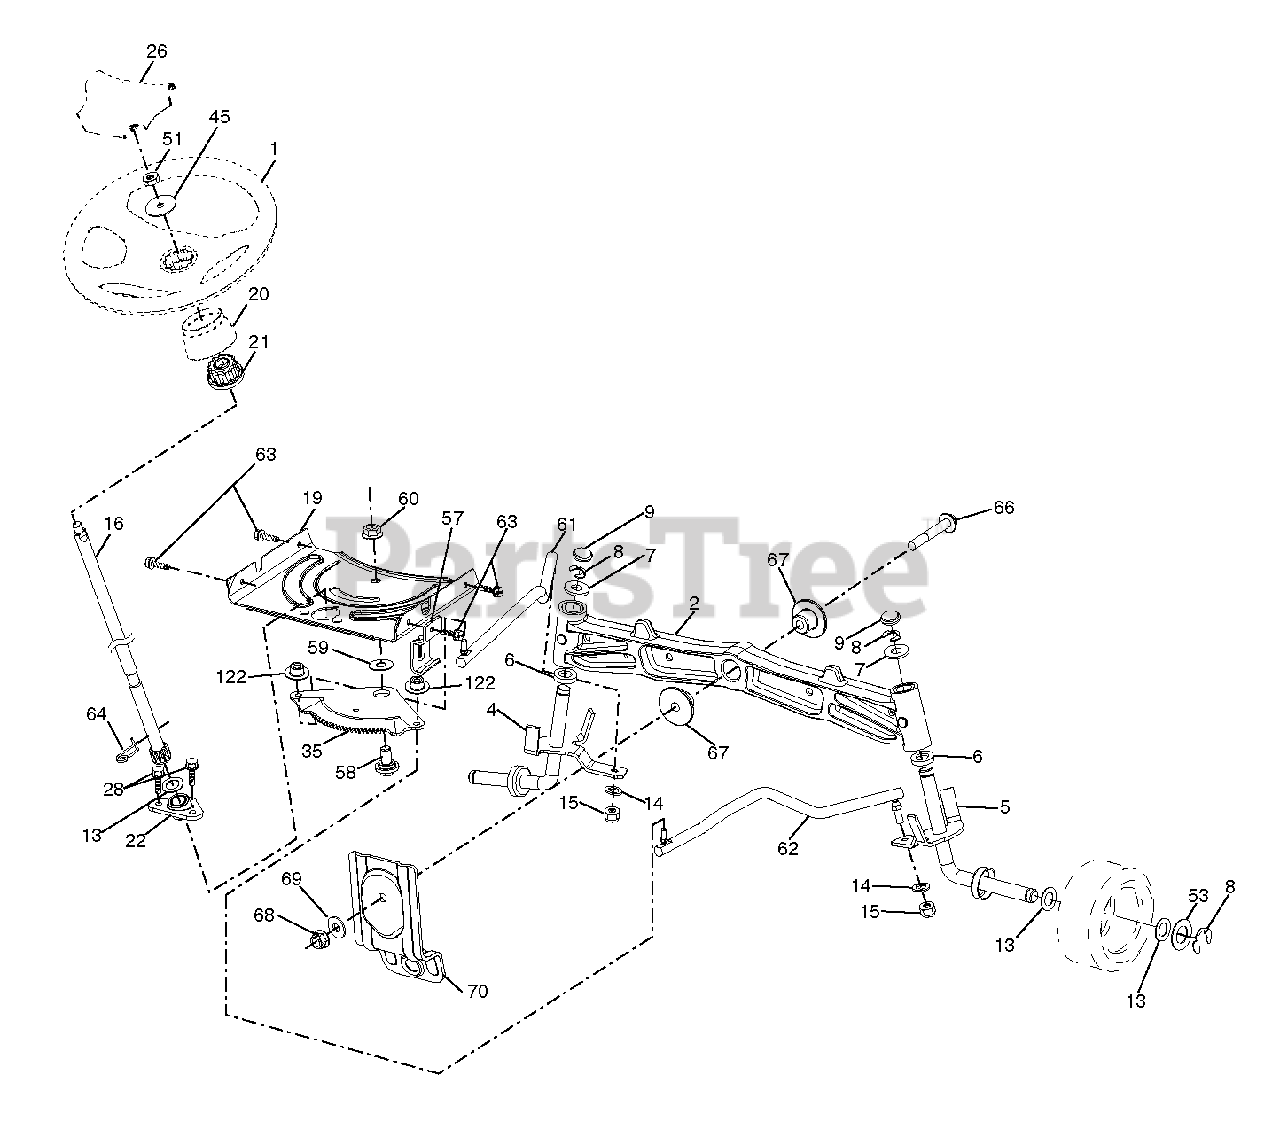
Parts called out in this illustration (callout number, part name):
1	WHEEL.STEERING.STDSRR.BLK/OV
4	SPINDLE.WELDED.LH.16"TEX
5	SPINDLE.WELDED.RH.16"TEX
8	RING CLIP
9	CAP.SPINDLE
14	WASHER, LOCK 3/8
15	NUT CROWNLOCK 3/8-24
19	PLATE.STEER.DDL.NLT/NG
20	BOOT.STEERING.
22	STEERING.SUPT.LOWER.
26	INSERT, WHEEL STEERING
28	SCREW, 3/8-16X3/4
35	GEAR.SECTOR.PLATE.DDL.
45	WASHER.11/32
51	NUT.HEX.1/2-20
53	WASHER.HARDENED
57	BRKT.UPSTOP.GT/LT.TEX
58	BOLT.SHOULDER.SECTOR.P
59	WASHER.THURST.SECTOR.S
60	NUT FLANGE LOCK 5/8-11
61	DRAGLINK.LH.BALLSTUD.D
62	DRAGLINK.RH.BALLSTUD.D
64	RETAINER.CLIP.SPRING.S
66	BOLT HEX FGHD 7/16-14 X 3 SERR
67	BUSHING.PM.FRONT AXLE
68	NUT.LOCK.FLANGE.7/16
69	WASHER.1.5X.505X.118
70	BRKT.DECK.SUSPENSION.F
